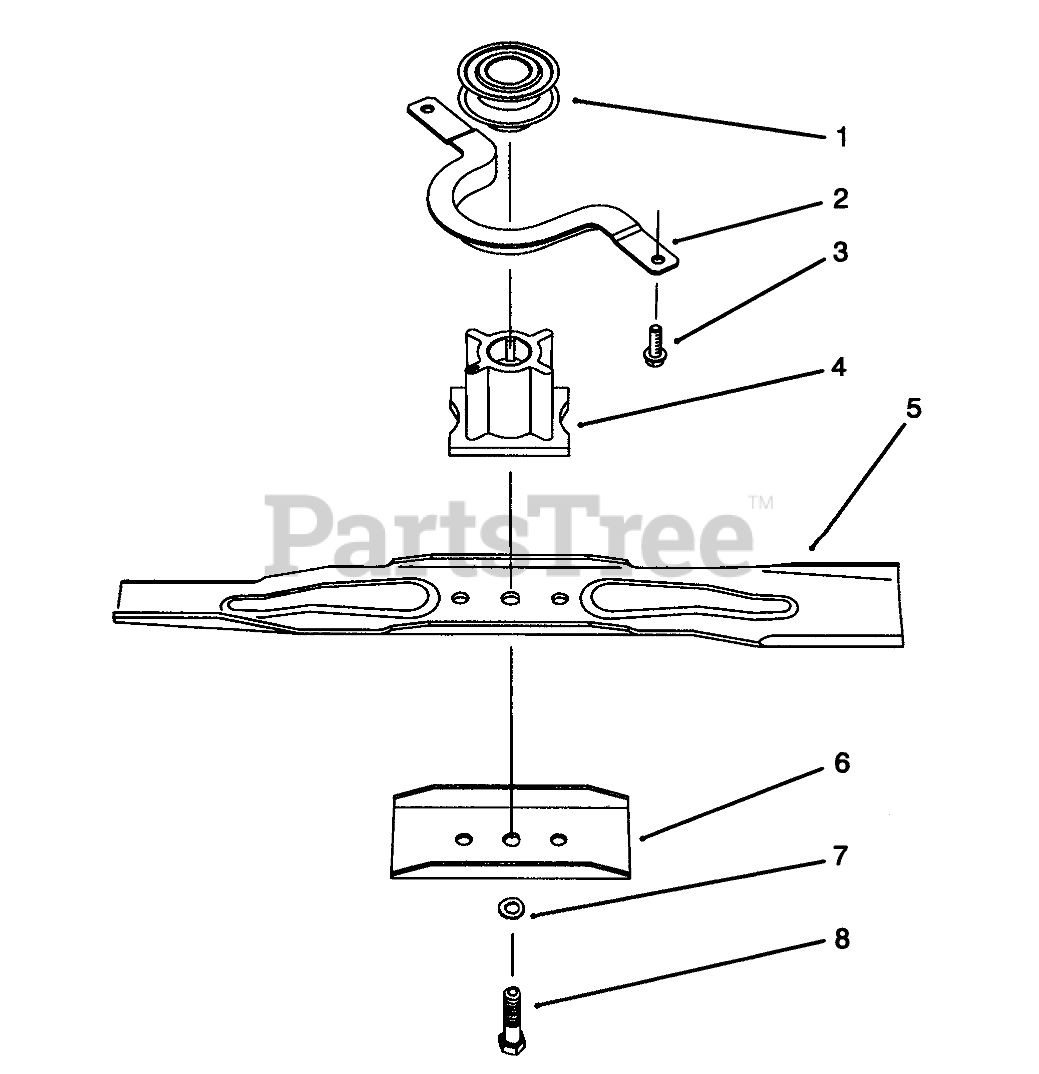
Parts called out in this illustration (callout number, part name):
1	PULLEY-DRIVE, ZONE START
2	Guide-Belt
3	SCREW-HWH
4	BLADE RETAINER - 25 MM
5	Blade
6	Stiffener Blade
7	WASHER-LOCK
8	BOLT-BLADE
